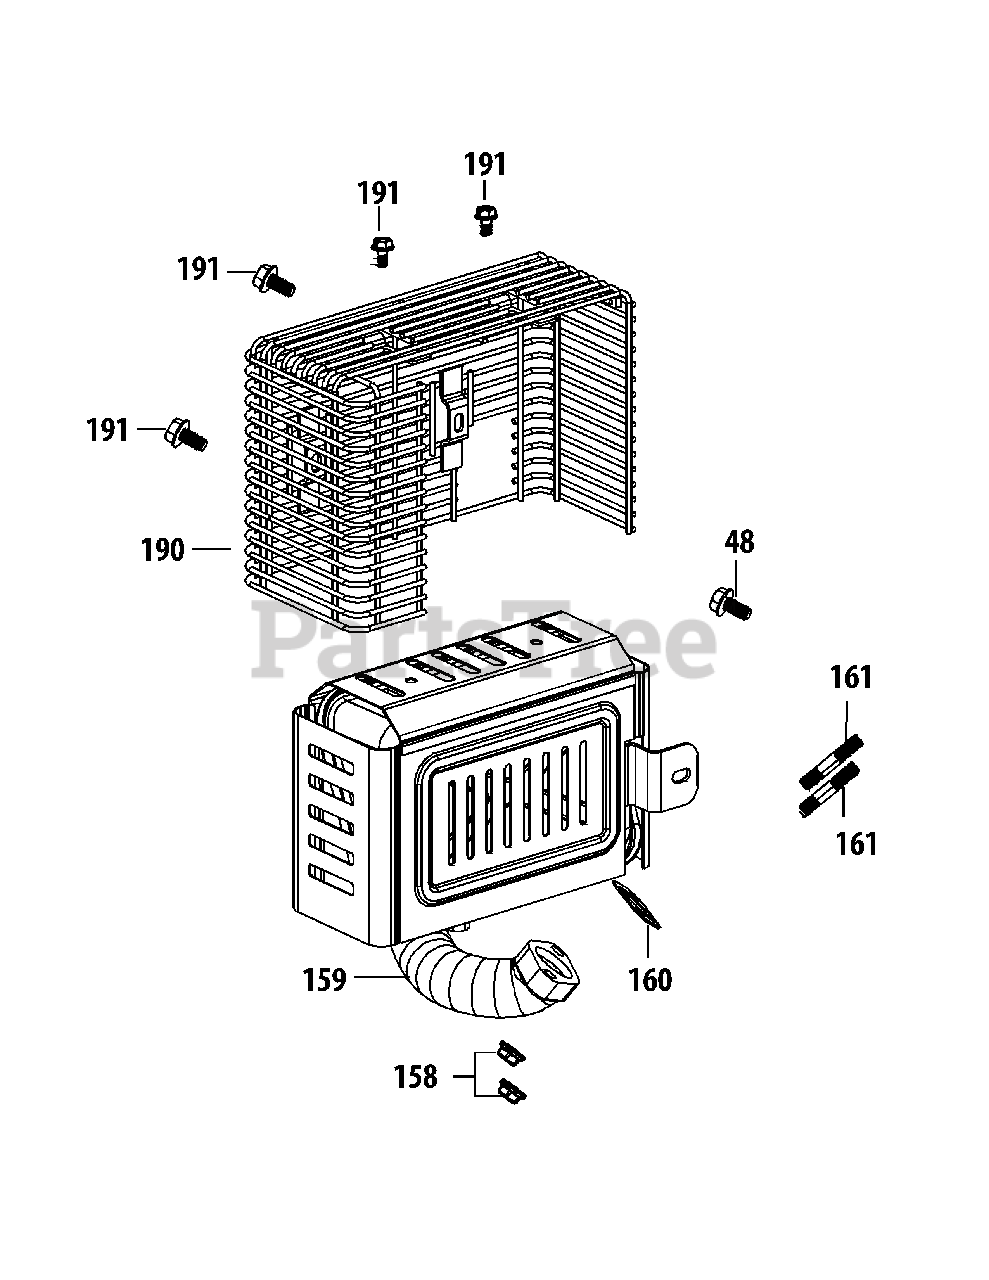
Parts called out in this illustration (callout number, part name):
48	Bolt M6×14
159	Muffler Assembly
160	Exhaust Pipe Gasket
161	Muff Stud M8×47
161	Muffler Stud Assembly
190	Wire Mesh Shield
191	Bolt M6×12
